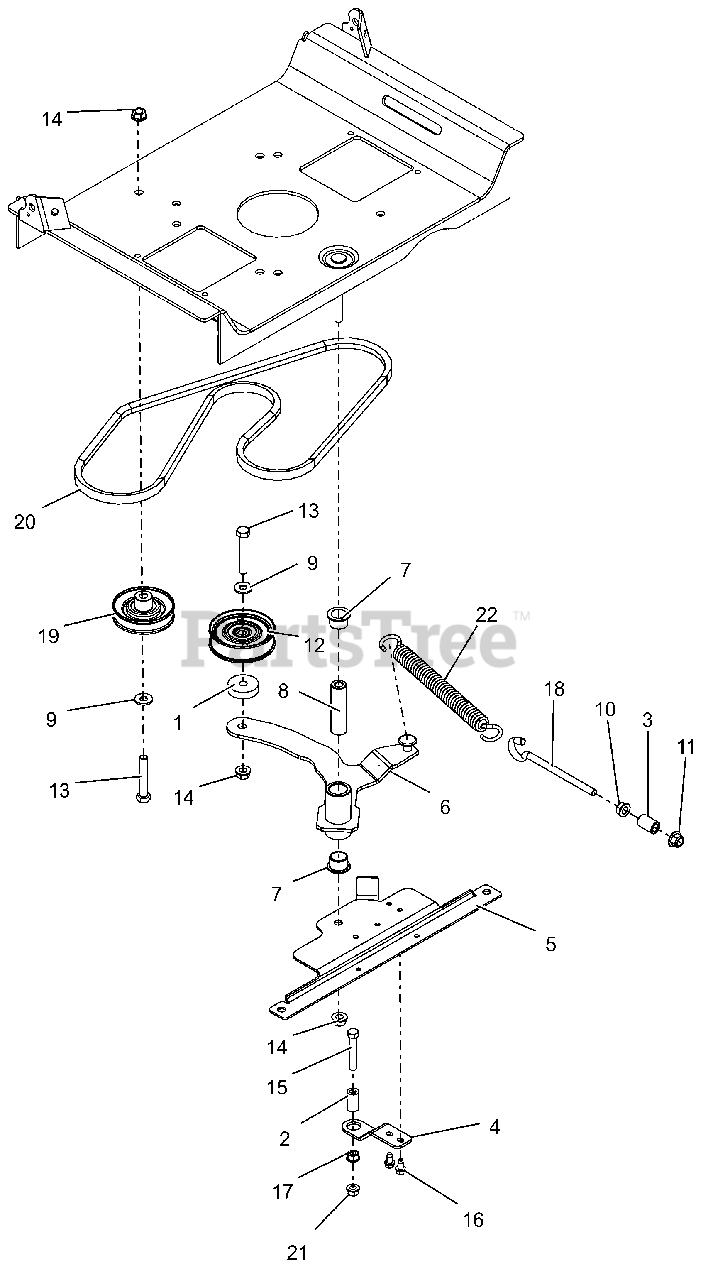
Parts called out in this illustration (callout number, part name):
1	SPACER, .39 X 1.50 X .380
2	SPACER, RUBBER 5/16 IDX1.0 LG
3	SPACER, .375X.625X.970 (PM)
4	BRKT, CLUTCH STOP
5	BRKT, IDLER ATTACHMENT (BLACK)
6	WLDMT,GRD DRIVE IDLER ARM-LGR
7	BSHG-FLG 0.75X0.875X.625X1.125
8	BUSHING, SLEEVE .38X.750X2.78
9	WSHR,FLT .375X.875X.083 ZCC
10	NUT, SPNLK-FLG .38-16 G5 ZCC
11	NUT,NYL-FLG .38-16 GF ZCC
12	IDLER, FLAT - 3.05" X .75"
13	BLT,HEX .38-16X2.25 G5 ZCC
14	NUT-LK-TOP-FLG .38-16 ZC120
15	BLT, HEX .31-18X2.00 G5 ZCC
16	SCR-TAP .25-20X.50 HWH ZCC
17	NUT,SPNLK-FLG .31-18 G5 ZCC
18	BOLT,.38-16 X 4.25-.62 DIA EYE
19	IDLER, V-3.000 OD
20	V-BELT, A-RAW EDGE
21	NUT-LK-TOP-FLG .312-18 GF ZCC
22	SPRING, EXTENSION
